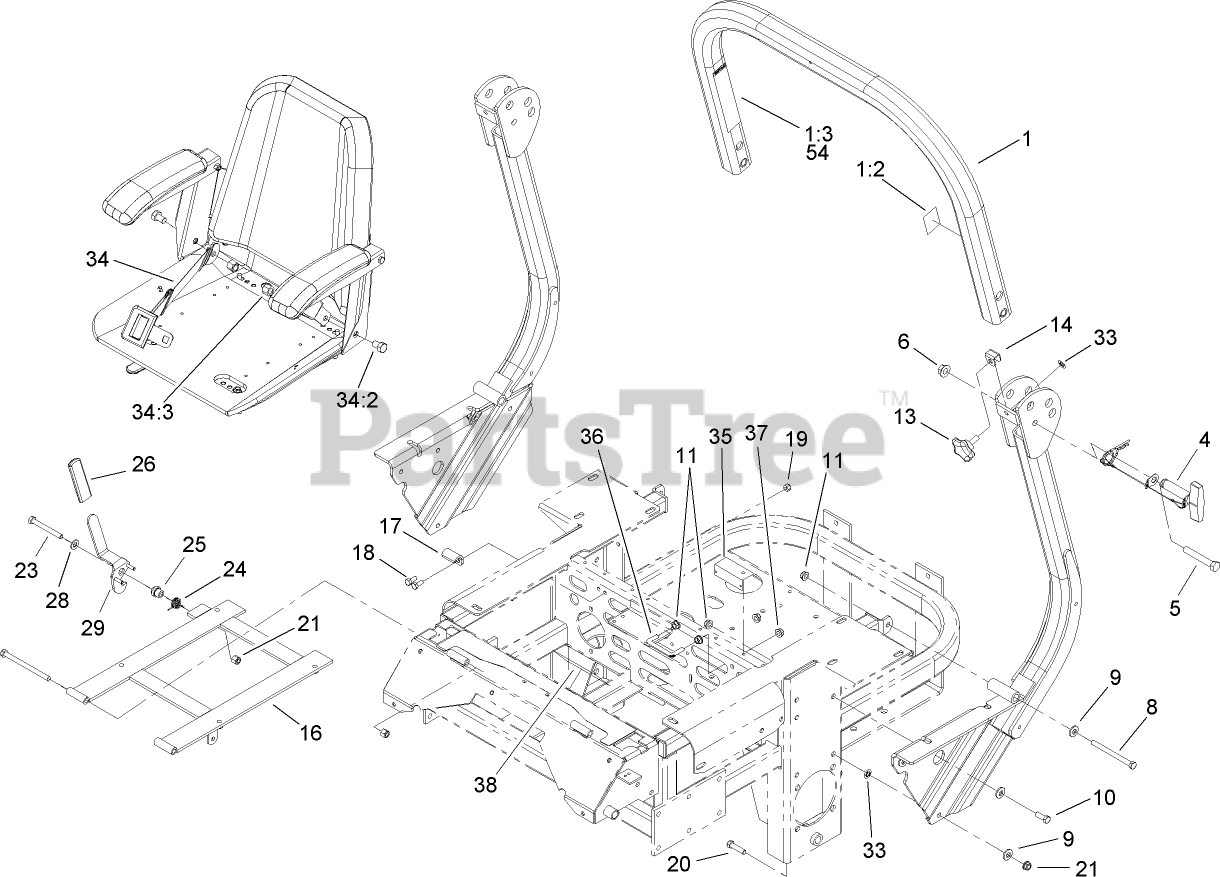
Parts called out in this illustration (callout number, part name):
1	Upper Tube ASM
1:2	DECAL-ROPS
1:3	DECAL-WARNING, FOLDING ROPS
4	PIN LATCH ASM
5	SCREW-HH
6	NUT-HF
8	SCREW-HH
9	WASHER-BELLEVILLE
10	SCREW-HH
11	NUT-HHF, WHIZ
16	SEAT SUPPORT FRAME ASM
17	Catch-Latch, Seat
18	SCREW-HH
19	NUT-LOCK, NI
20	SCREW-HH
21	NUT-LOCK, NI
23	SCREW-HH
24	SPRING-TORSION
25	BUSHING-LATCH, SEAT
26	GRIP-HANDLE
28	WASHER-FLAT
29	LATCH ASM
33	NUT-PUSH
34	SEATBELT KIT
34:2	SCREW-HH
34:3	NUT-LOCK, NI
35	TEMPLATE-DRILL, SEAT CATCH
36	U-BOLT
37	NUT-HF
38	DECAL-WARNING
54	DECAL-WARNING
